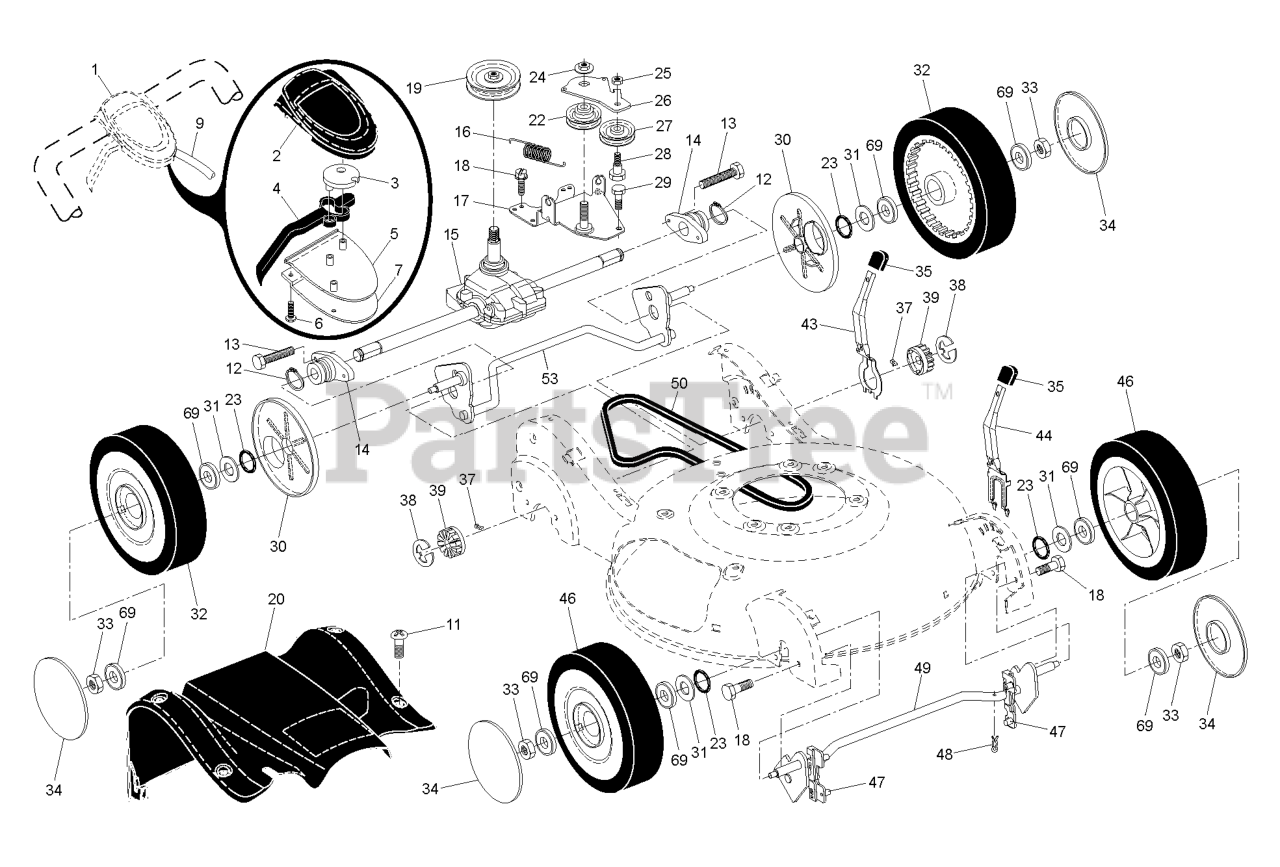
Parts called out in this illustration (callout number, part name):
3	HEIGHT ADJUSTER
5	BEARING FLANGE
7	NUT
8	WASHER
10	LOCKNUT M8
13	BOLT
14	CONNECTION ROD
